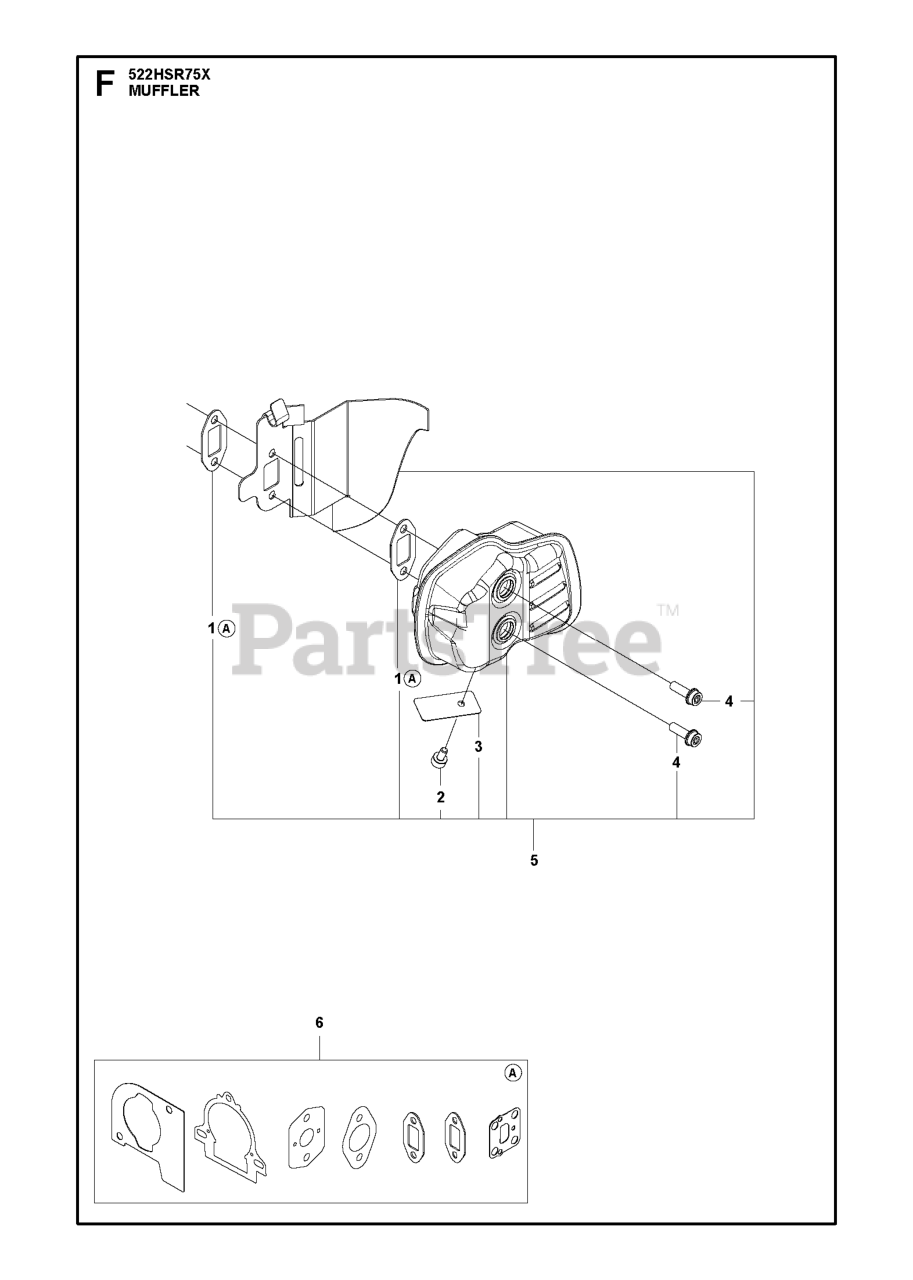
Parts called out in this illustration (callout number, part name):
1	GASKET MUFFLER
2	SCREW ITXSCM
3	SPARK ARRESTER
5	MUFFLER ASSY
6	GASKET KIT 522
